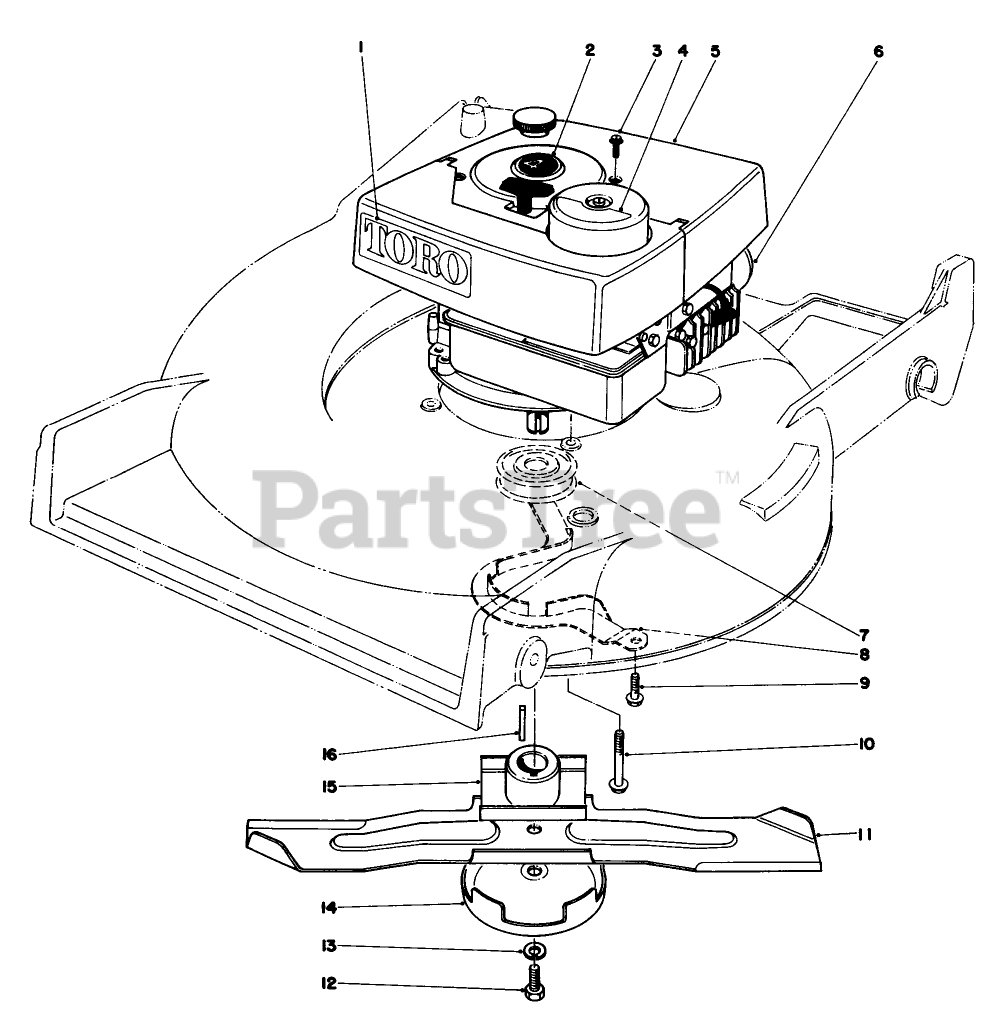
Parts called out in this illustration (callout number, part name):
2	Decal-4 Cycle
6	Engine
12	SCREW-BLADE
13	WASHER-LOCK
